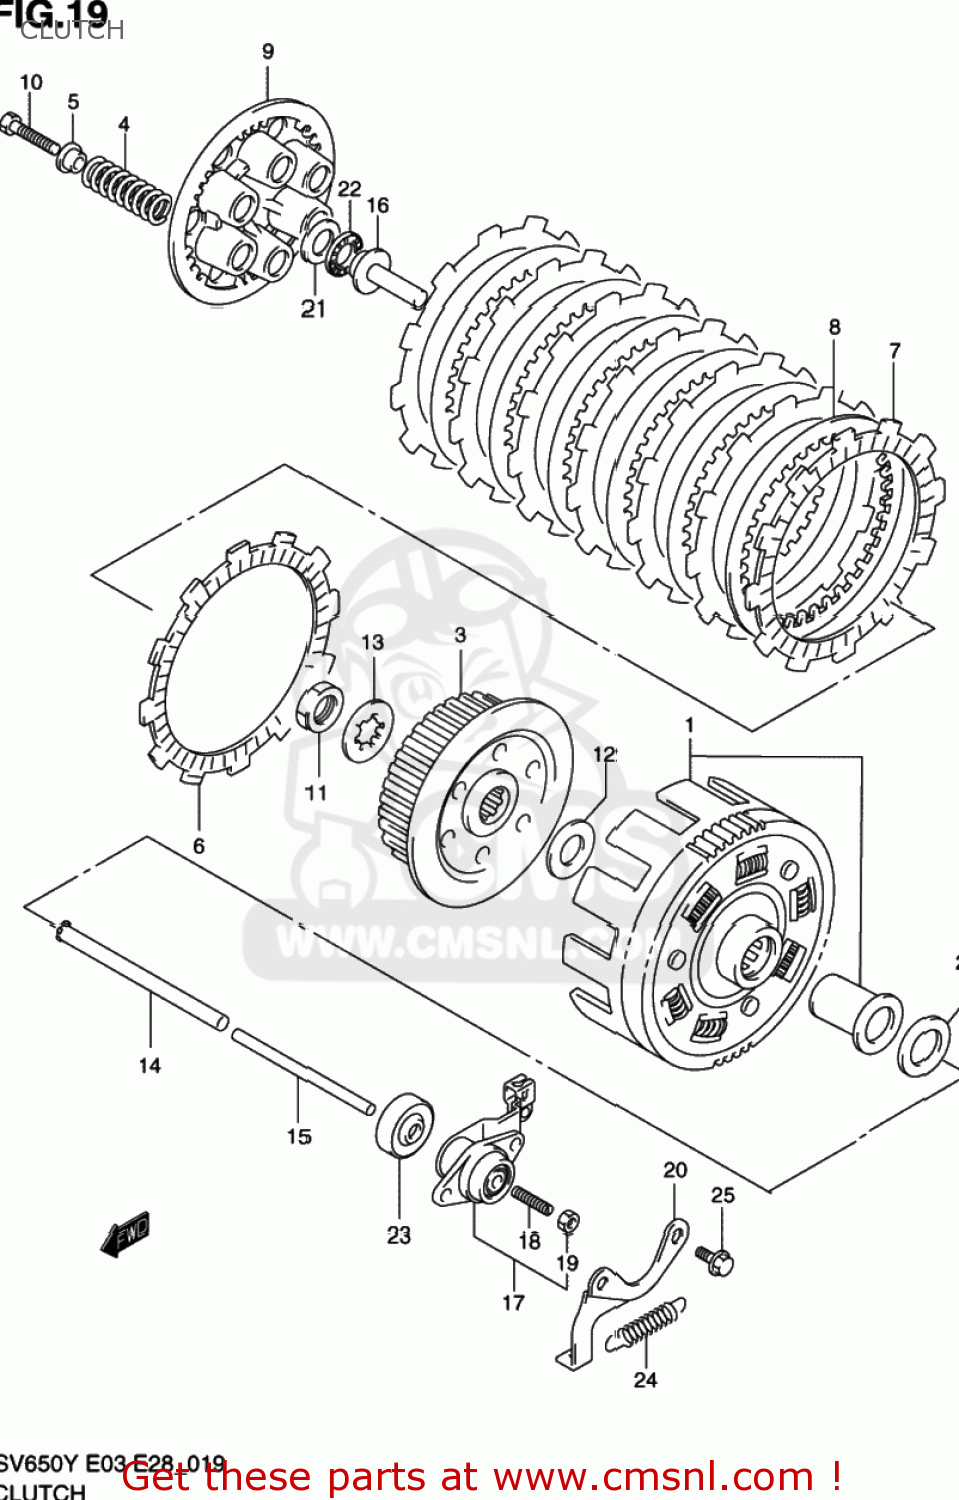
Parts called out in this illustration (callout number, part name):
1	GEAR ASSY,PRI DRIVEN
2	WASHER(20X36X3)
3	HUB,CLUTCH SLEEVE
4	SPRING,CLUTCH
5	SPACER,CLUTCH SLEEVE HUB
6	PLATE,CLUTCH DRIVE (NAS)
7	PLATE,CLUTCH DRIVE (NAS)
8	PLATE,CLUTCH DRIVEN(T:1.6) (NAS)
9	DISC,CLUTCH PRESSURE
10	BOLT(6X40)
11	NUT
12	WASHER(20X36X3)
13	WASHER,LOCK
14	ROD,PUSH,R
15	ROD,CLUTCH PUSH,L
16	PIECE,CLUTCH PUSH
17	SCREW ASSY,CLUTCH RELEASE
18	SCREW(6X25)
19	NUT
20	SUPPORT,CLUTCH RELEASE RETURN
21	WASHER(15.5X28X1)
22	BEARING(15X28X2)
23	SEAL,OIL(6X34X5.5)
24	SPRING
25	BOLT
